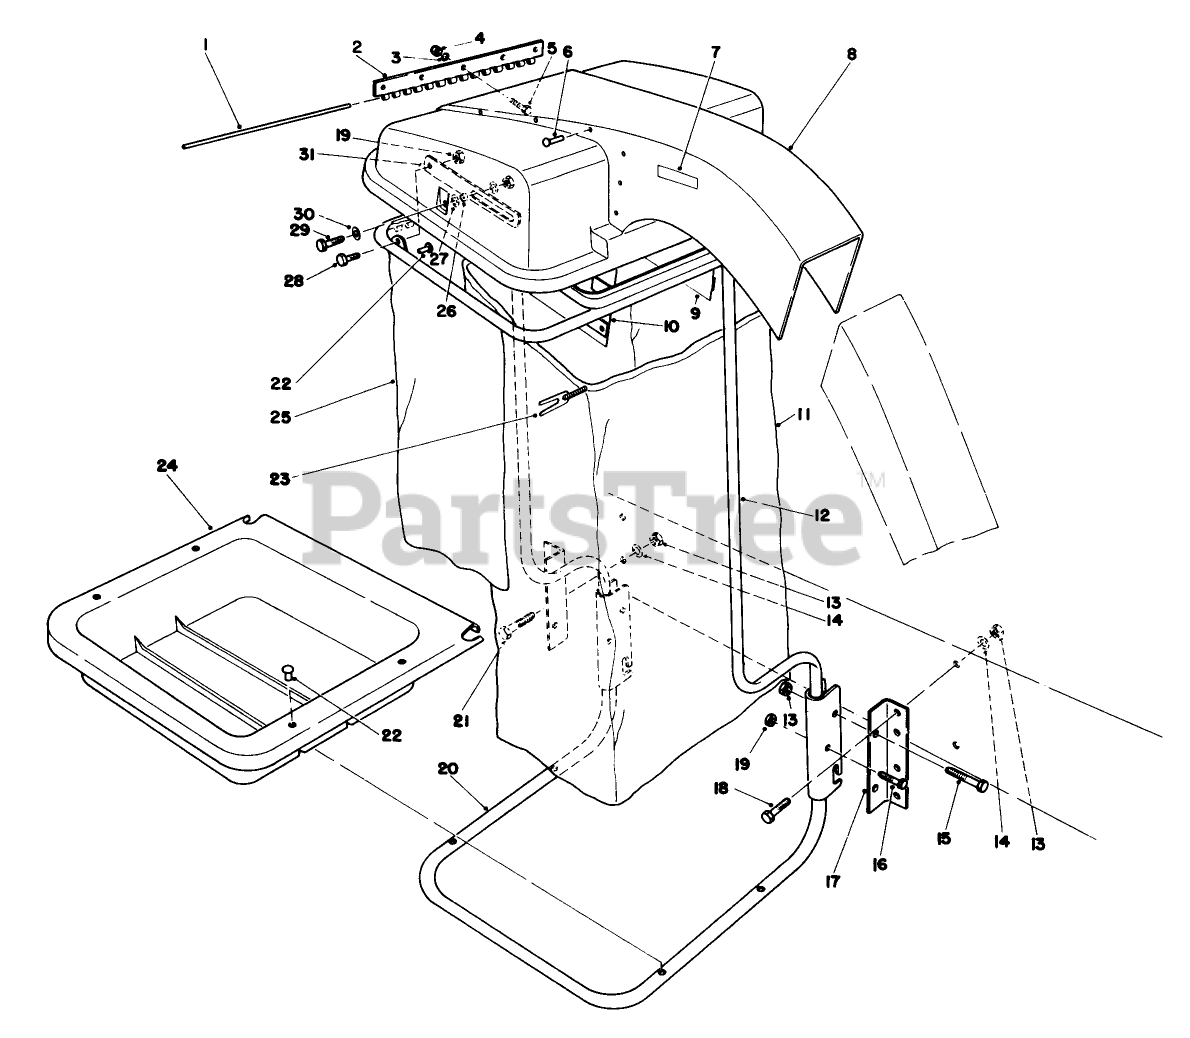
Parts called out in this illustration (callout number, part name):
1	HOOD HINGE PIN
2	Hinge-Half
3	WASHER-FLAT
4	NUT-LOCK, NI
6	RIVET-BLIND
7	Decal-Caution
8	Hood Assembly (Incl. Ref. #2-7, 9 & 10)
9	Screen Left Hand
10	Screen Right Hand
11	BAG-CLOTH, 32"
12	Support Tube Assy. Upper (Incl. Ref. #22 & 25)
13	NUT-LOCK, CONE
14	WASHER-FLAT
15	SCREW-HH
16	SCREW-HH
17	BRKT-FRAME B
18	SCREW-HH
19	NUT-LOCK, CONE
20	Support Tube Assy.-Lower (Incl. Ref. #22 & 24)
21	SCREW-HH
23	BAG CORD FASTENER
24	Tray Lower
25	Skirt-Bagging Frame
26	SPACER - PIVOT ARM
27	WASHER-FLAT
28	SCREW-HH
29	SCREW-HH
30	WASHER-FLAT
31	Stop-Hood
